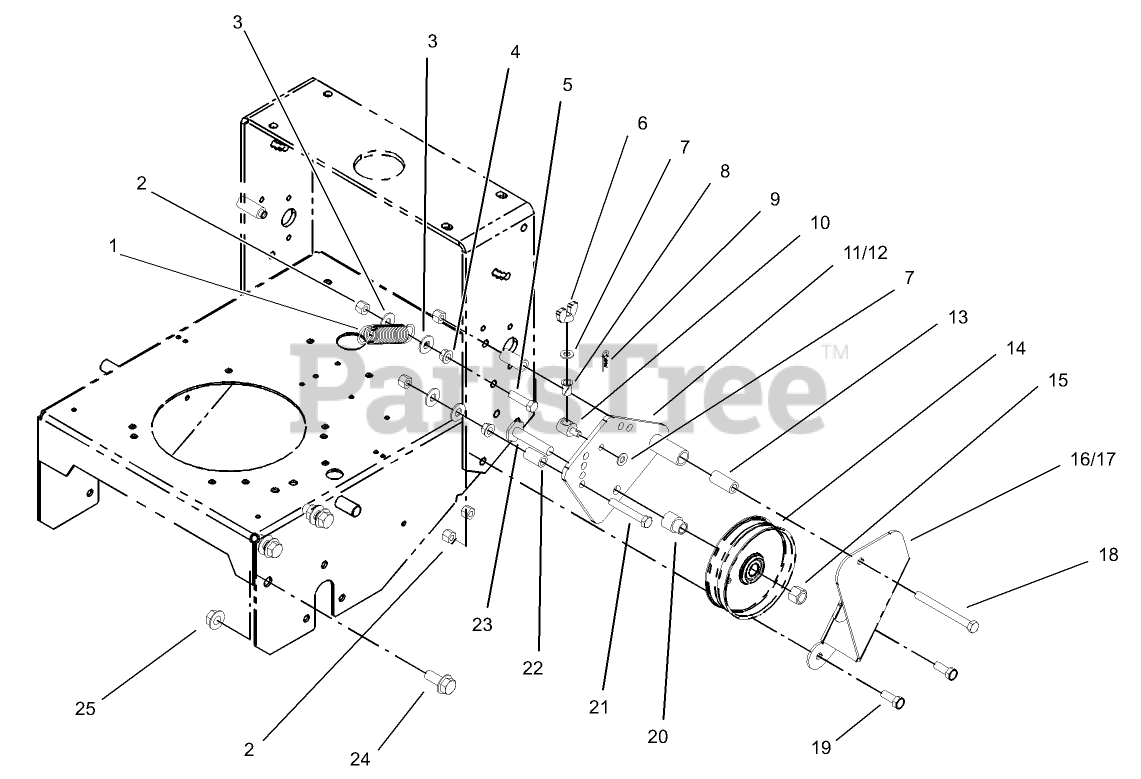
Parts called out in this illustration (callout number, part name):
1	SPRING-EXTENSION
2	NUT-LOCK, NI
3	WASHER-FLAT
4	NUT-FLANGE
5	SCREW-HH
6	NUT-WING
7	WASHER-PLAIN
8	BUSHING-NYLON
9	PIN-COTTER
10	FITTING-ROD
11	LH IDLER BRACKET ASM
12	RH IDLER BRACKET ASM
13	SPACER-PIVOT, IDLER
14	PULLEY-IDLER
15	NUT-LOCK, NI
16	BRACKET-SUPPORT, LH
17	BRACKET-SUPPORT, RH
18	SCREW-HH
19	SCREW-HH
20	SPACER-PULLEY
21	SCREW-HH
22	SPACER
23	SCREW-LEVELER
24	SCREW-HHF
25	NUT-HF
